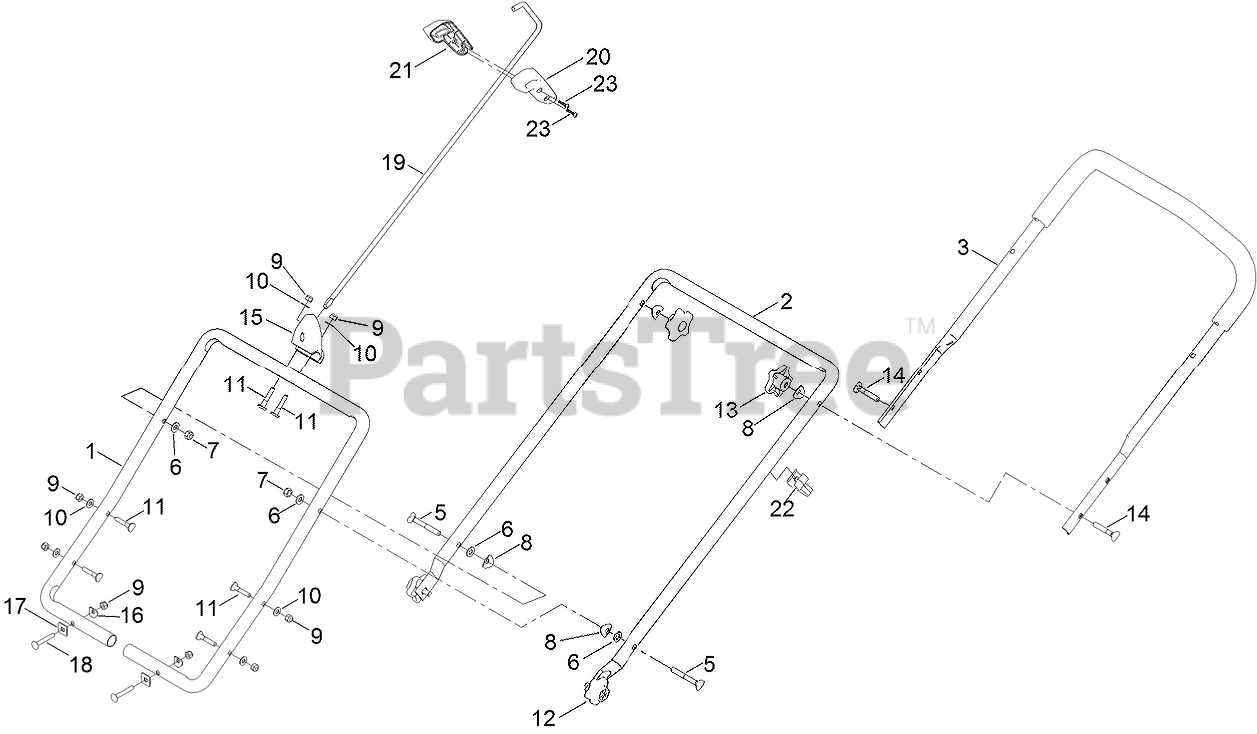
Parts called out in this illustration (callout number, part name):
1	HANDLE-LOWER
2	HANDLE-MIDDLE
3	UPPER HANDLE ASM
5	SCREW-HANDLE
6	WASHER-FLAT
7	NUT-LOCK, NI
8	WASHER
9	NUT-LOCK, NI
10	WASHER-FLAT
11	SCREW-HANDLE
12	KNOB-HANDLE
13	KNOB-LOCKING, HANDLE
14	SCREW-HANDLE
15	GUIDE-ROD, CHUTE
16	WASHER
17	WASHER-SQUARE
18	SCREW-CARR
19	ROD-CONTROL, CHUTE
20	GRIP-LH
21	GRIP-RH
22	GUIDE-CABLE
23	SCREW-PPH
